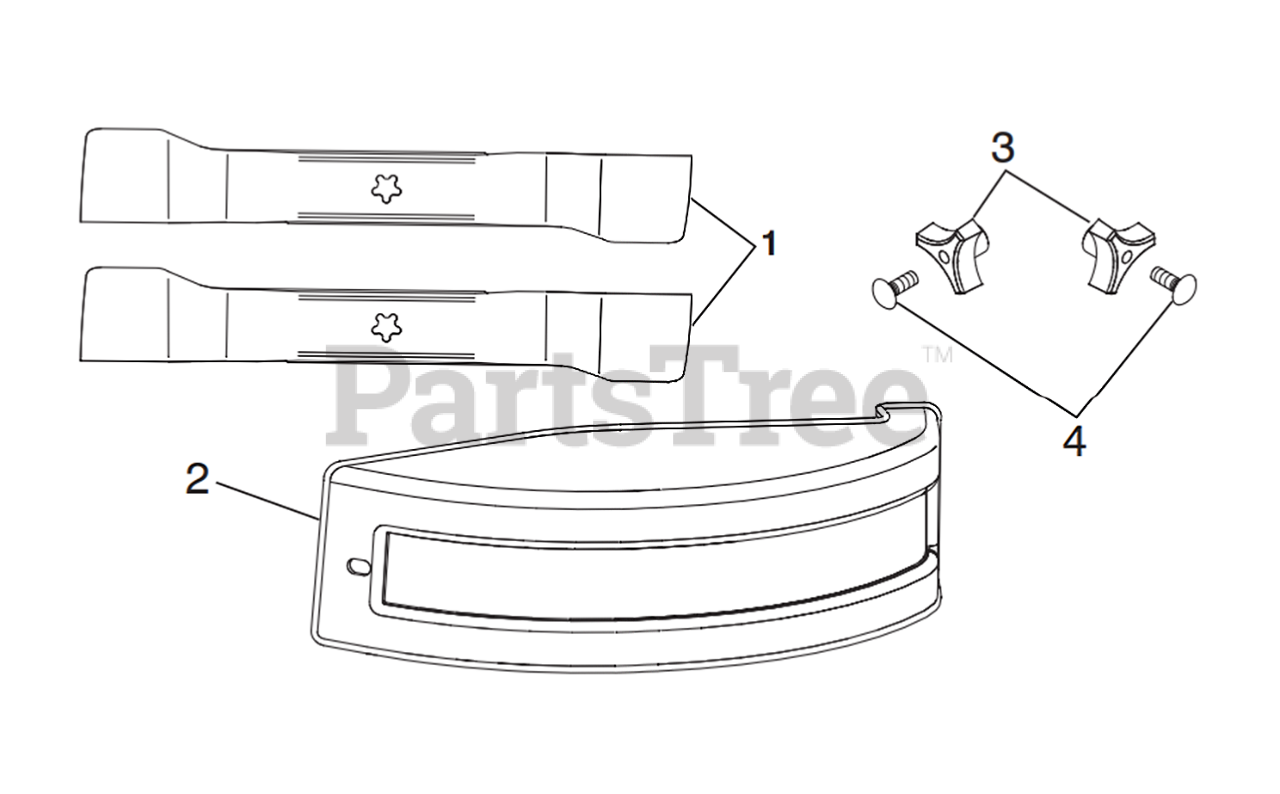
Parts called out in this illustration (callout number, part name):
1	BLADE 42 FCS MULCH BLADE EDIP
2	COVER.MULCH.42.FCS
3	KNOB.HANDLE.3/8.TRI-POINT.BLAC
